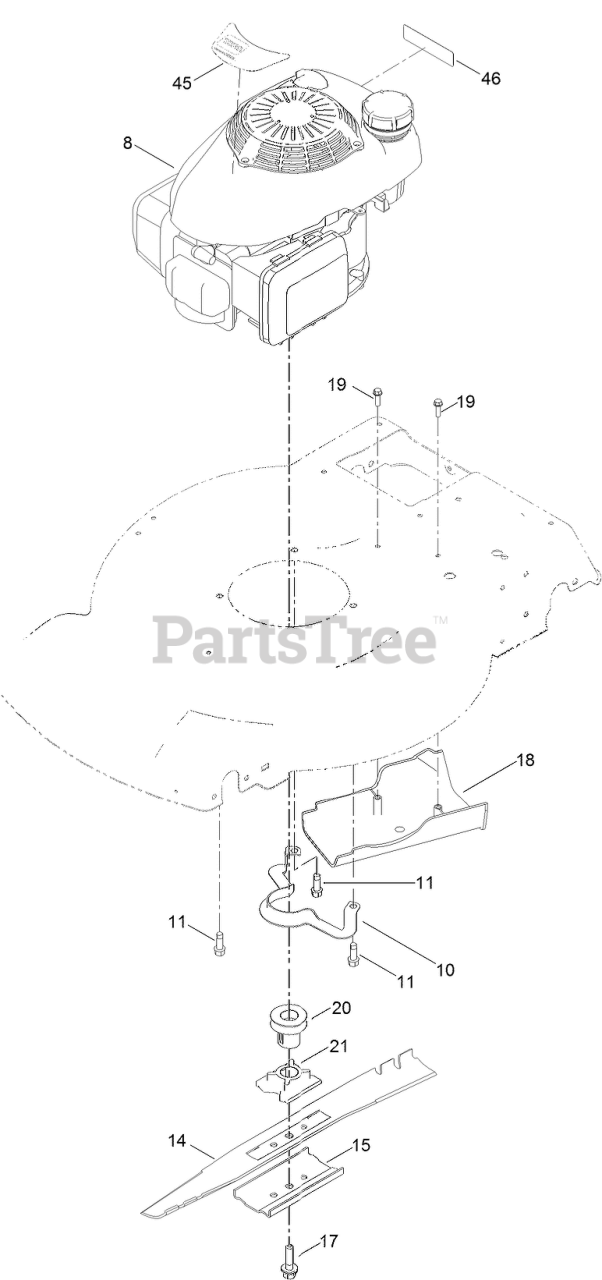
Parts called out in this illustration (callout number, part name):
10	GUIDE-BELT
11	SCREW-TAPTITE
14	BLADE-22 INCH
15	SUPPORT-BLADE
17	BOLT-BLADE
18	COVER-BELT
19	SCREW-HWH
20	PULLEY
21	RETAINER-BLADE
45	DECAL-SHROUD, HONDA
46	DECAL-ARRESTOR, SPARK
